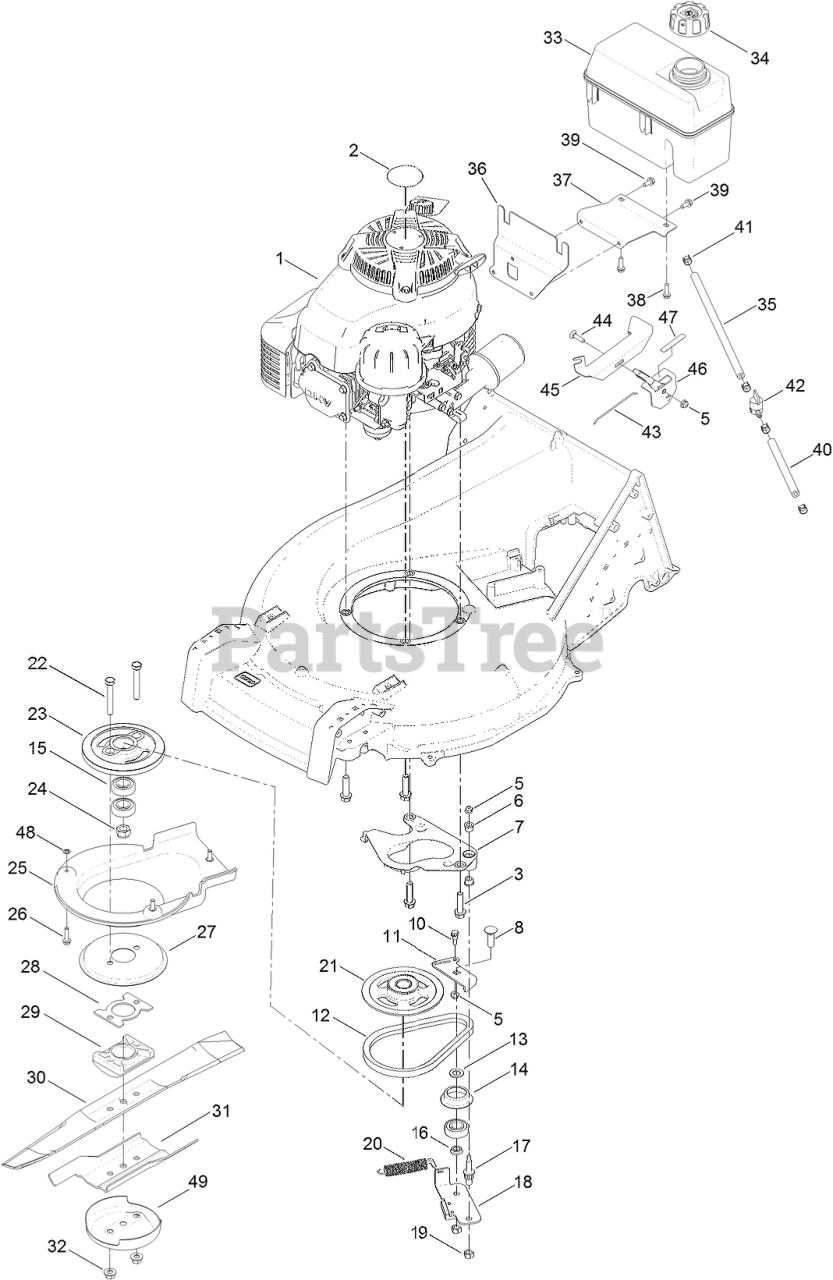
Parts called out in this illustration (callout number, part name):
3	SCREW-HWH
5	NUT-HF
6	BUSHING-FLANGE
7	PLATE-ANCHOR
8	BOLT-CARR
10	BOLT-SHOULDER
11	PLATE-GUIDE, BBC
12	BELT
13	WASHER-PLAIN
14	RETAINER-BELT
15	BEARING-BALL
16	SPACER-BEARING
17	BOLT-SHOULDER
18	PLATE-BRAKE
19	NUT-HEX
20	SPRING-TENSION, BRAKE
21	PULLEY
22	SCREW-HH
23	DRUM
24	NUT-HEX
26	SCREW-HWHTF
27	DISC
28	SPACER-DRIVER, BLADE
29	SUPPORT-BLADE
30	BLADE-RECYCLING
31	ACCELERATOR-BLADE
32	NUT-FLANGE, LOCK
33	TANK-FUEL
34	CAP-GAS
35	HOSE-FUEL
36	BRACKET-TANK, MOUNTING
37	BRACKET-TANK, SUPPORT
38	SCREW-HWH
39	SCREW-HWH
40	HOSE-FUEL
41	CLAMP-HOSE
42	VALVE-FUEL
43	WIRE-CONTROL
44	SCREW-CARR
45	BRACKET-MOUNT, THROTTLE
46	CONTROL-THROTTLE
47	DECAL-THROTTLE, CHOKE
48	NUT-RETAINER
49	CUP-ANTI SCALP
